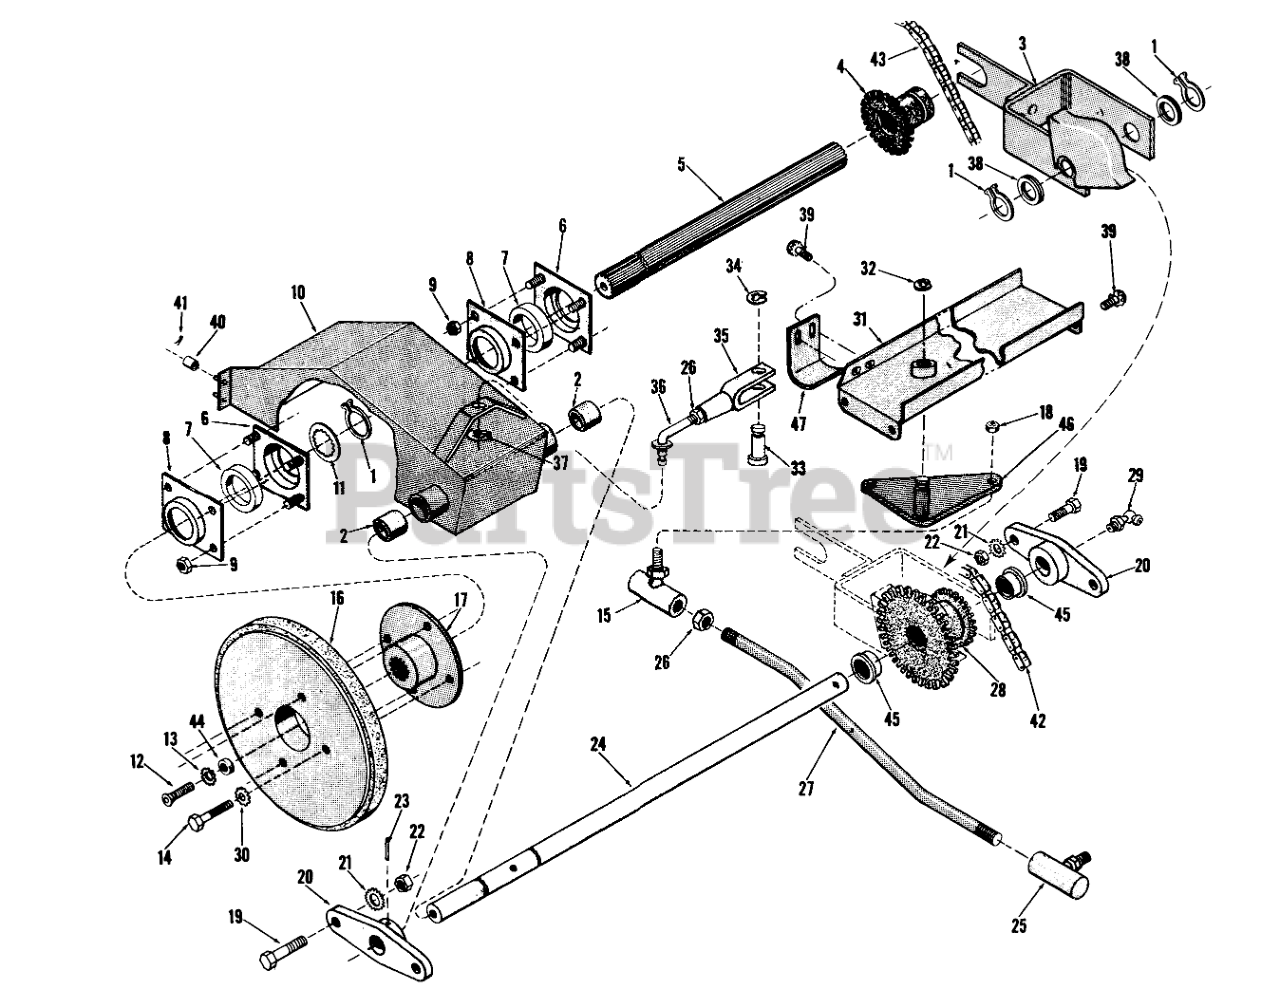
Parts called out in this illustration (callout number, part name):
1	Ring-Snap
2	BUSHING
3	Bracket
4	Sprocket
5	Drive Shaft
6	Bearing Retainer
7	Bearing
8	Bearing Retainer
9	NUT-KEPS
10	Engaging Bracket
11	Washer
13	Lockwasher
14	SCREW-HH
15	Ball Socket
16	Disc
17	Hub Assy.
18	NUT-LOCK NI
19	SCREW-HH
20	Shaft Retainer
21	WASHER-LOCK
22	NUT-HEX
23	PIN-ROLL
24	Dead Shalt
25	Ball Socket
26	NUT-JAM
27	Connecting Rod
28	Sprocket Assy. with Bushings
29	FITTING-GREASE, 90 DEG
30	WASHER-LOCK
31	Support
32	Snap Ring
33	Yoke Pin
34	RING-RETAINING, EXT
35	YOKE
37	Nut-Lok
38	Nyliner
39	1/4-20X1/2 THDG SEMS
40	Roller Pivot
41	PIN-COTTER
42	Chain
43	Chain
44	Washer
45	3/4IDX1LG FLANGE BSHG
46	Bell Crank Shift
47	Chain Guard
